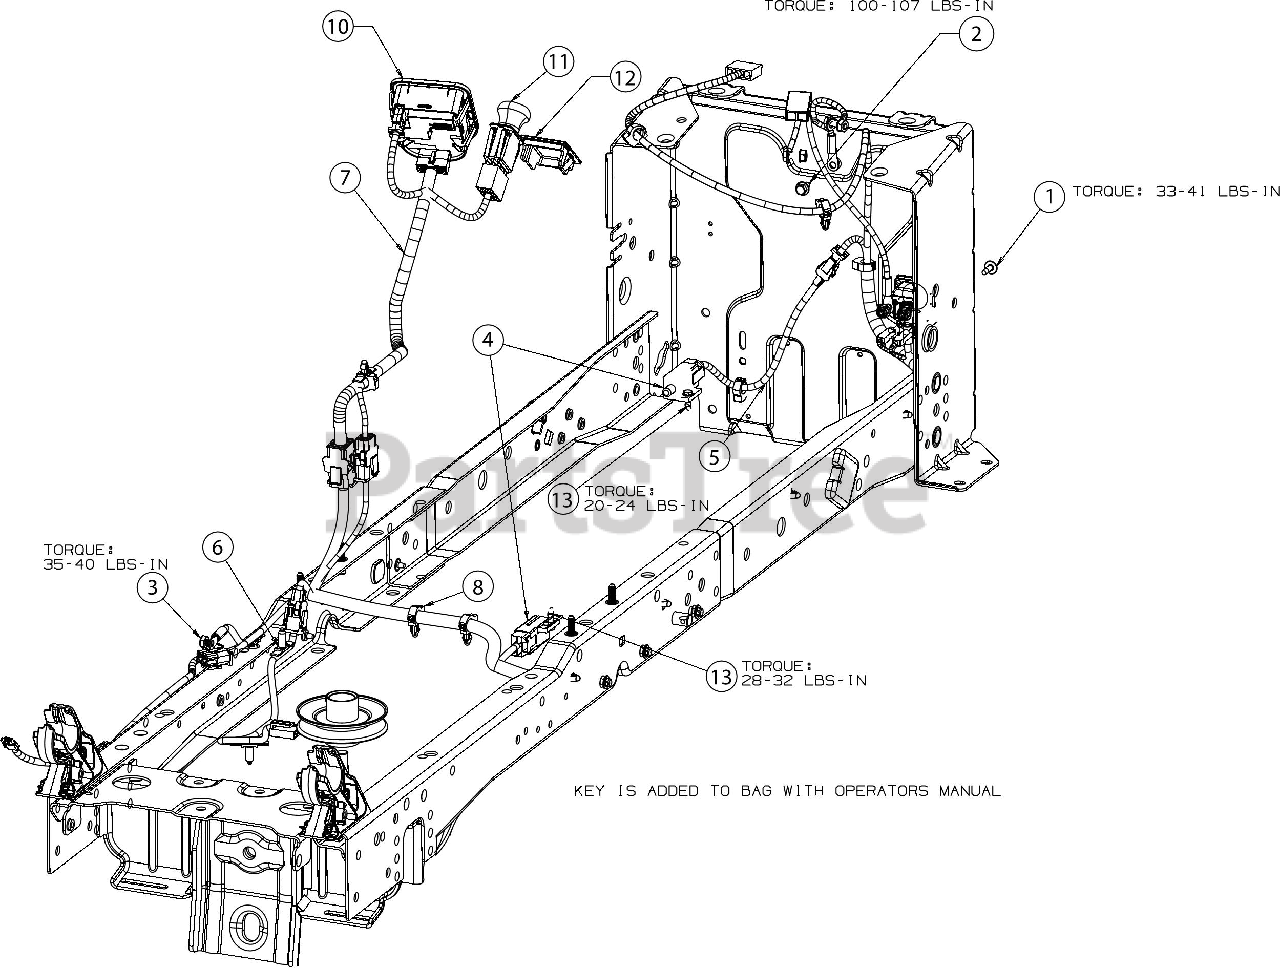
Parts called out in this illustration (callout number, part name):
1	SCREW M6-1 x .625
2	SCREW 1/4-20X.625
3	HEX NUT 1/4-20
4	INTERLOCK SWITCH (NO/NC)
5	REVERSE HARNESS
6	CLUTCH HARNESS 11"
7	MAIN HARNESS E-PTO/PBS/RMC
8	DASH HARNESS E-PTO/PBS/RMC
10	MODULE-PBS/HRMTR/SVC MNDR/BT
11	PTO SWITCH (YELLOW KNOB)
12	DASH HOUR METER PLUG
13	SHOULDER SCREW
